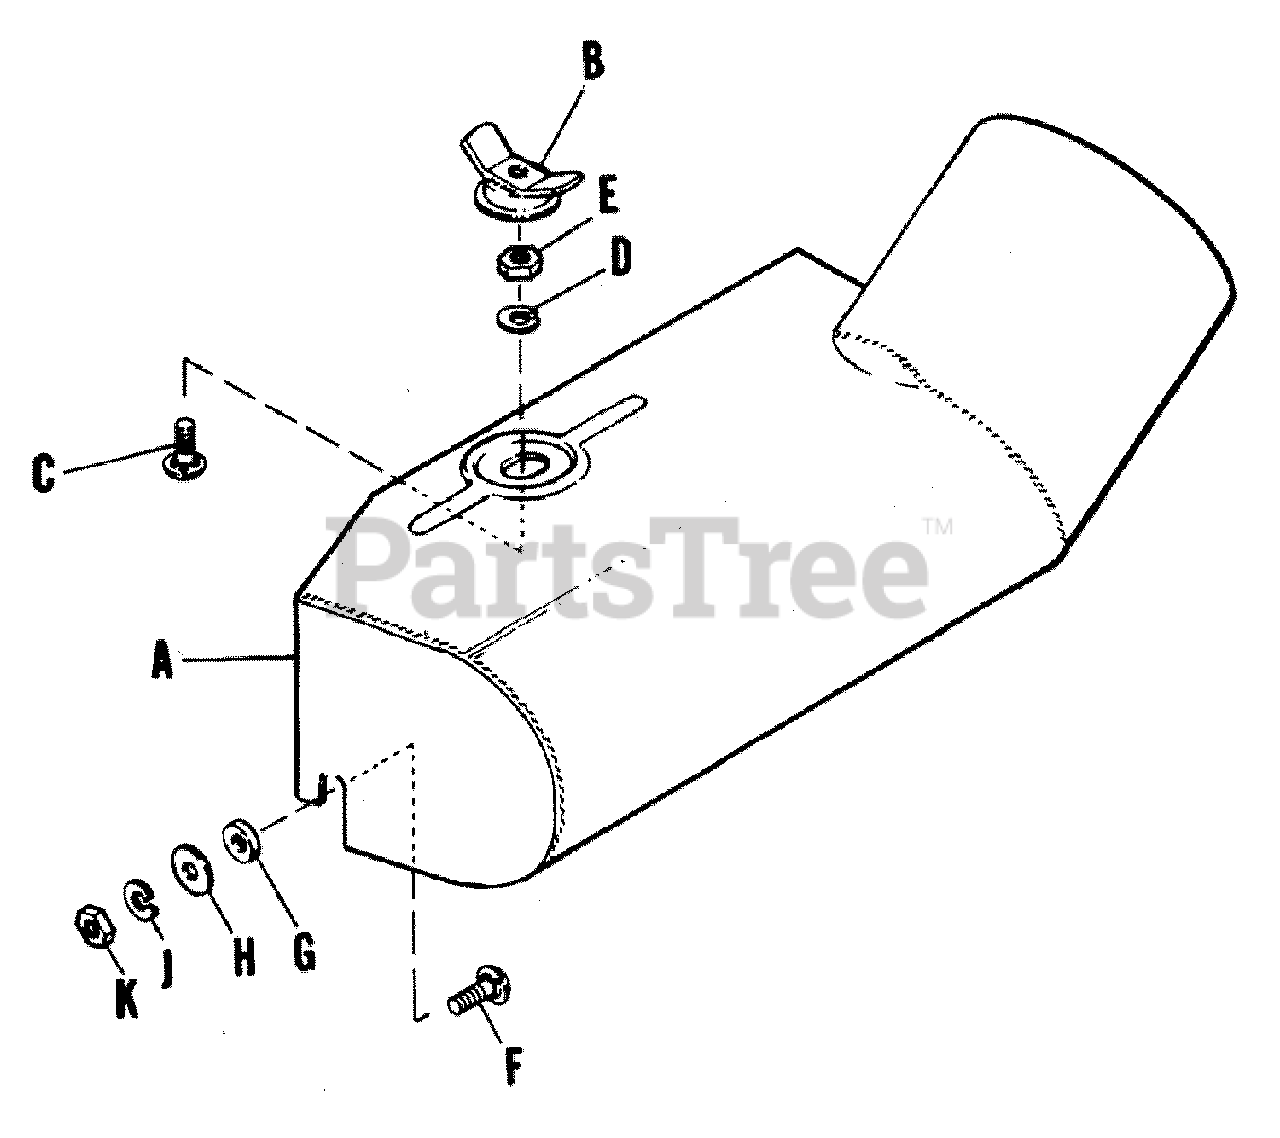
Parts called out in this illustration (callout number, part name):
A	HOSE ASSEMBLY
B	FLANGE, Hose
C	CLAMP, Hose
D	SCREW, Round Head, Slot, Machine, 1/4"-20 x 3"
E	WASHER, Lock, 1/4"
F	NUT, Hex, Full, 1/4"-20
G	HANDLE, Hose
H	HANDLE, Hose Clamp
J	CAPSCREW, Hex, 5/16"-18 x 3/4"
K	WASHER, Lock, 5/16"
